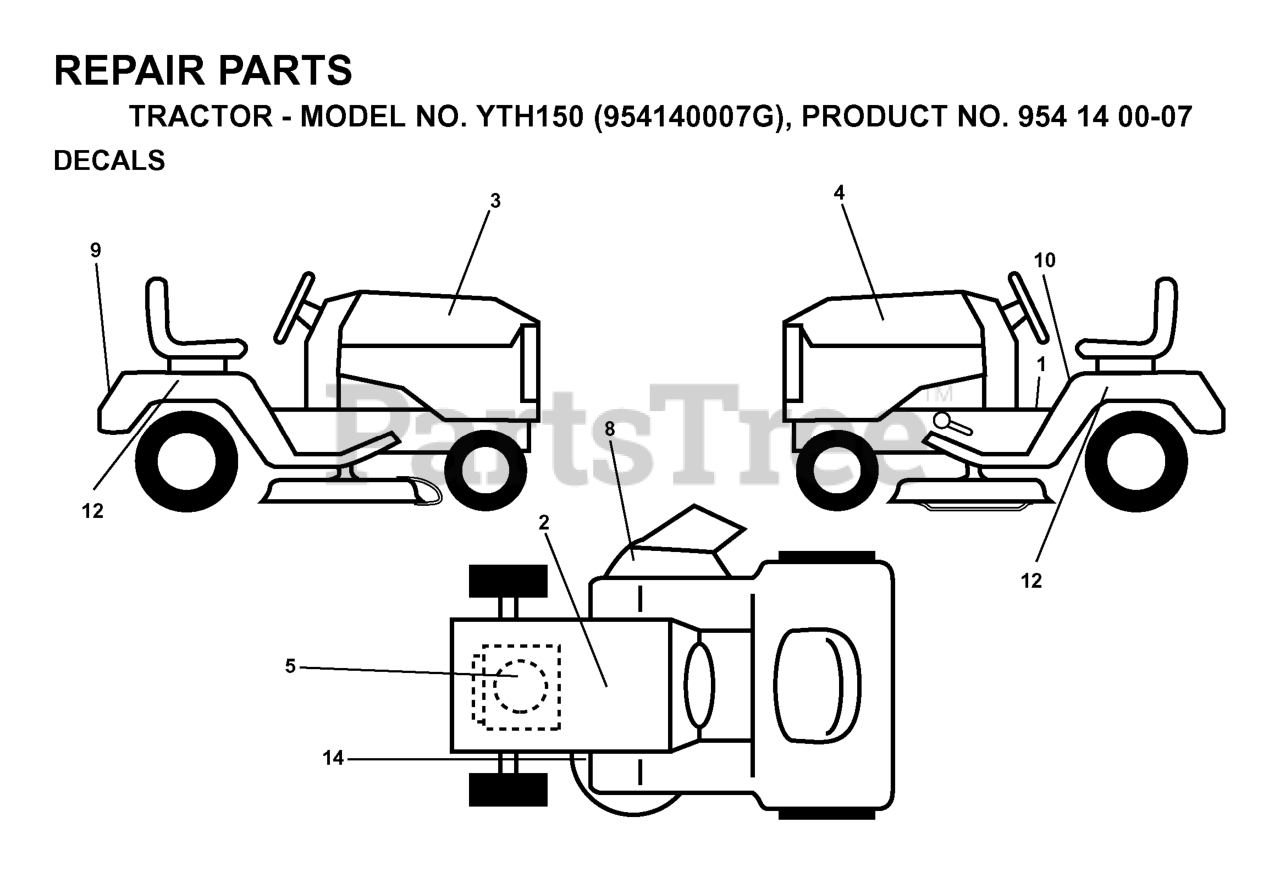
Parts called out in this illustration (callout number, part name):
2	DECAL BTRY SYMBOLS
3	DECAL, HOOD RH YTH150
4	DECAL, HOOD LH YTH150
8	DECAL WARNING (ENGLISH/FRENCH)
9	DECAL FENDER HUSQ
10	DECAL FENDER DANGER
14	DECAL V BELT SCHEMATIC
